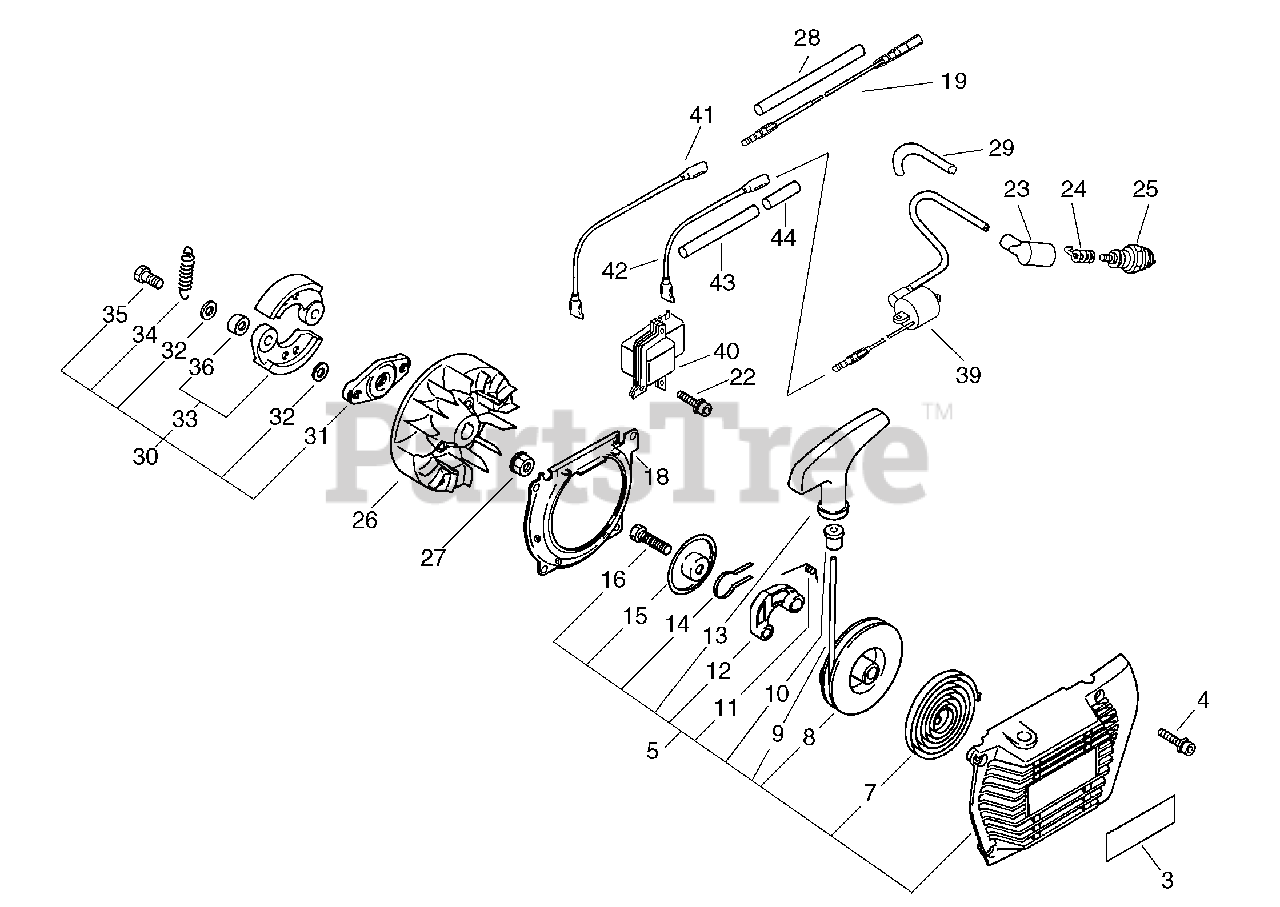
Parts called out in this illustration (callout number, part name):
3	LABEL - ECHO
4	SCREW - 5X22
5	STARTER ASSY
7	SPRING, REWIND
8	REEL, ROPE
9	ROPE, STARTER
10	GUIDE, ROPE
11	SPRING, RETURN
12	PAWL, STARTER
13	GRIP, STARTER
14	SPRING, FRICTION
15	PLATE, FRICTION
16	SCREW - 6X12
18	COVER, FAN
22	SCREW - 5X22
23	CAP, SPARK PLUG
24	TERMINAL, SPARK PLUG CAP
25	SPARK PLUG -- BPMR-8Y
26	FLYWHEEL
28	TUBE, INSULATOR
30	CLUTCH ASSY
31	HUB, CLUTCH
32	WASHER, CLUTCH
33	SHOE, CLUTCH
34	SPRING, CLUTCH
35	BOLT, CLUTCH
39	COIL, IGNITION
40	COIL, IGNITION
41	LEAD - GROUND
42	LEAD - IGNITION
44	TUBE
